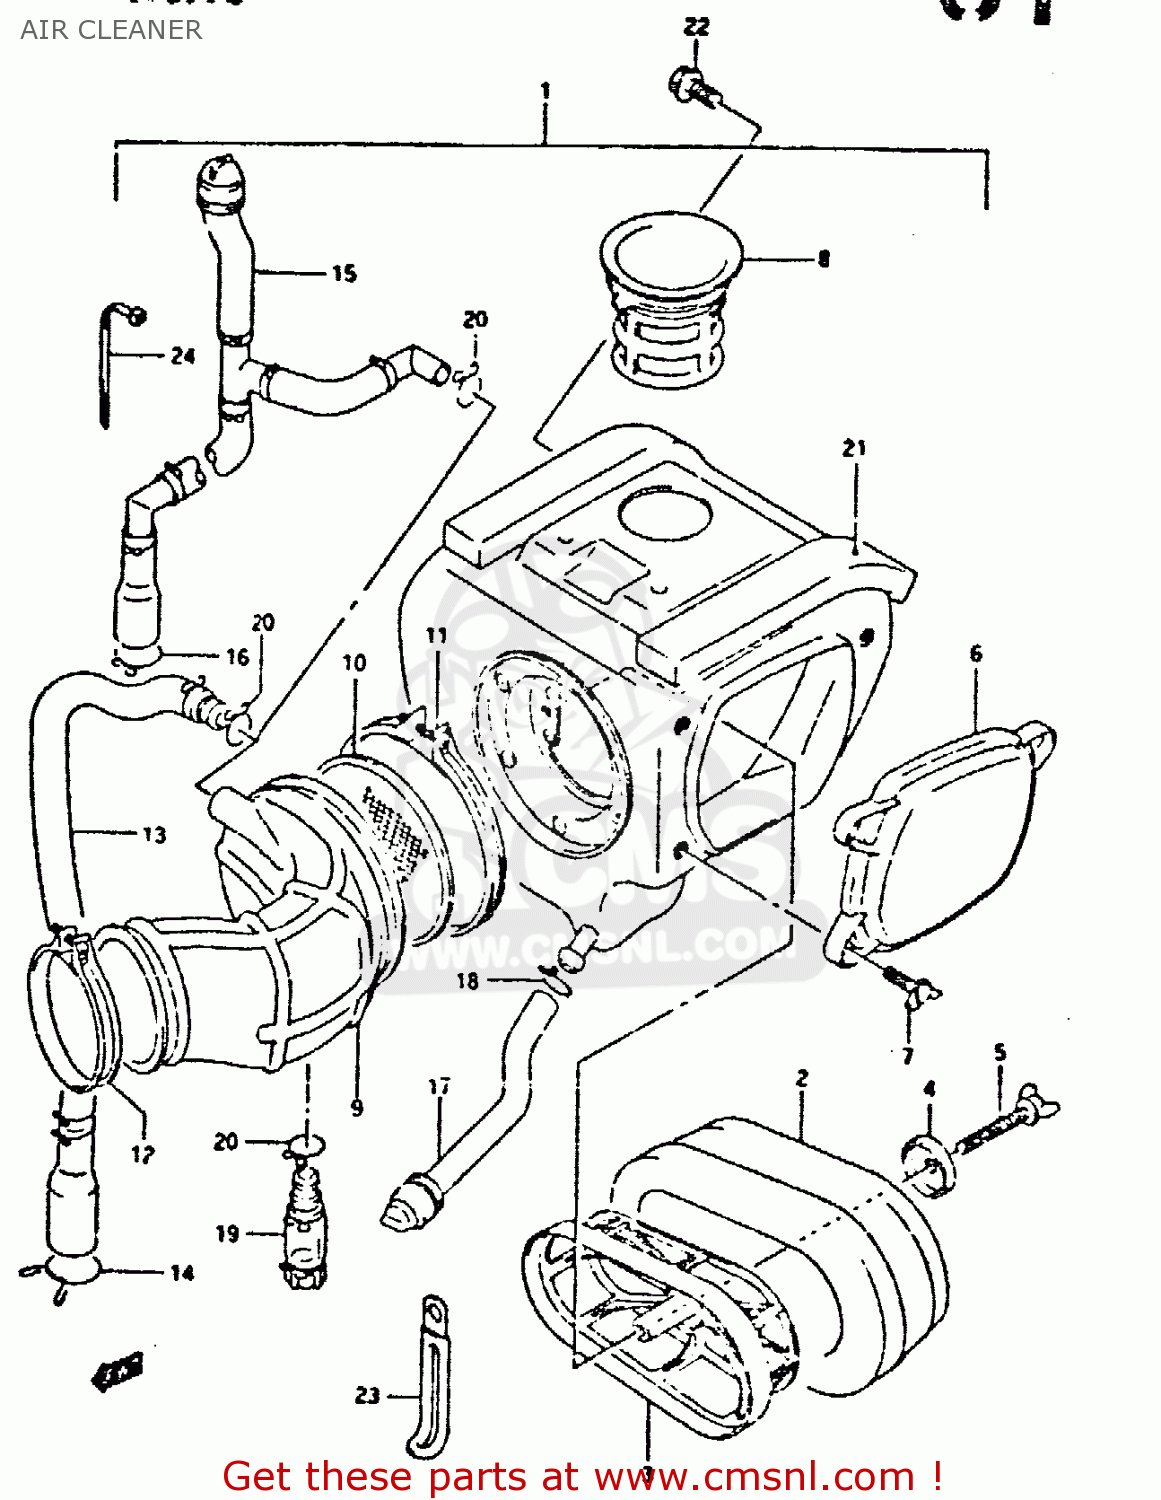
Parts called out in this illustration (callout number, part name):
1	CLEANER ASSEMBLY,AIR
2	FILTER
3	HOLDER,FILTER
4	WASHER,AIR CLEANER
5	BOLT,WING
6	CAP,AIR CLEANER
7	SCREW
8	TUBE,INLET
9	TUBE,OUTLET
10	TRAP,FRAME
11	CLAMP
12	CLAMP
13	TUBE,BREATHER
14	CLIP
15	TUBE,BREATHER
16	CLIP
17	TUBE,DRAIN A
18	CLIP
19	TUBE,DRAIN
20	CLIP
21	CUSHION
22	BOLT
23	CLAMP
24	CLAMP L:165
